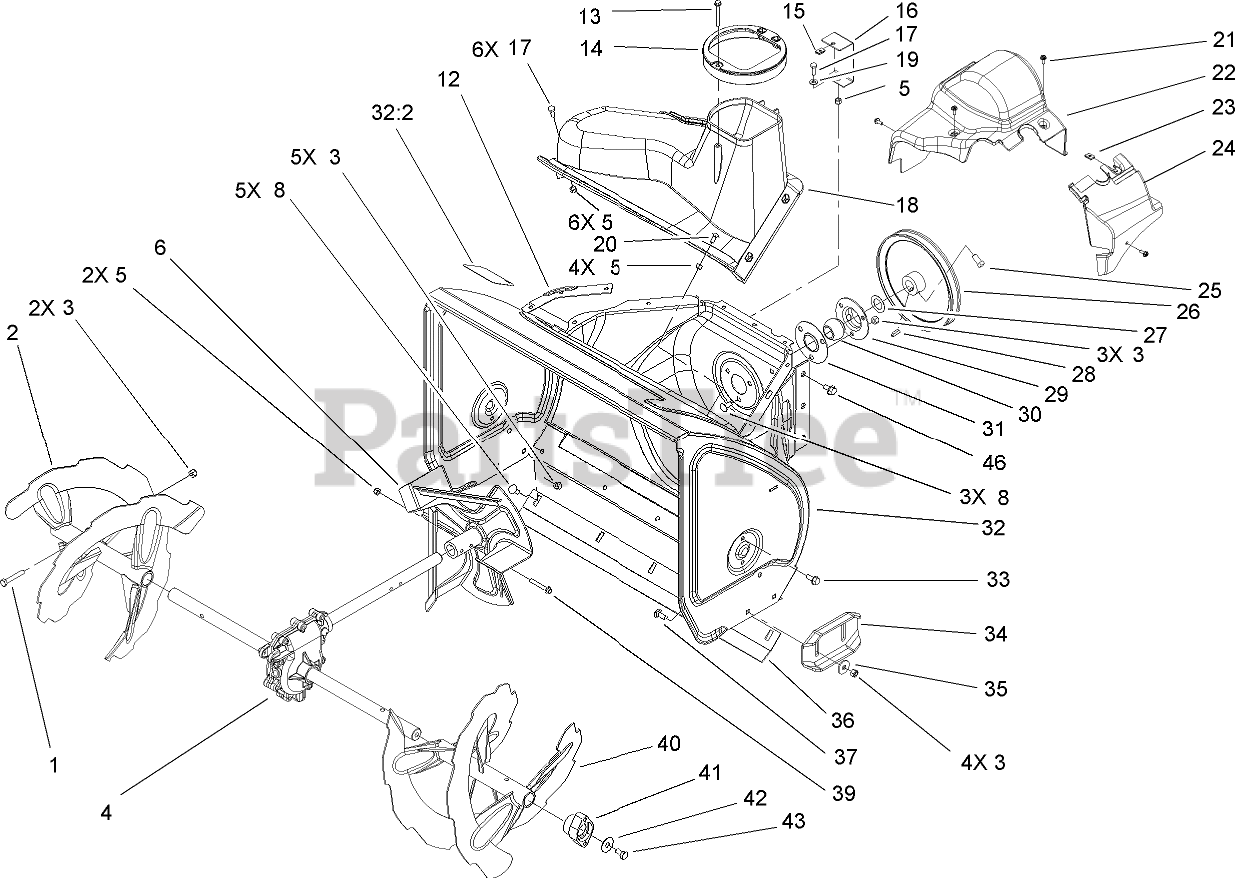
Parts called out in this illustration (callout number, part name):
1	SCREW-HH
2	RH AUGER ASM
3	NUT-LOCK, NI
4	26INCH AUGER GEARCASE ASM
5	NUT-LOCK, NI
6	IMPELLER ASM
8	SCREW-CARR
12	SEAL-FLANGE, COVER
13	SCREW-PLASTITE
14	GUIDE-CHUTE
15	NUT-SPEED, U-TYPE
16	BRACKET-COVER, CLIP NUT
17	SCREW-HH
18	COVER
19	WASHER-FLAT
20	BOLT-CARR
21	SCREW-HWH
22	COVER-BELT
23	NUT-SPEED
24	COVER-EXTENSION, BELT
25	SCREW-SET, SQH
26	PULLEY-IMPELLER
27	WASHER-THRUST
28	KEY-WOODRUFF
29	FLANGE-CUP, BEARING
30	BEARING-BALL
31	FLANGE-CUP, BEARING
32	HOUSING-AUGER, 26 INCH
32:2	DECAL-WARNING, AUGER
33	SCREW-HWHTF
35	WASHER
36	SCRAPER-FIXED
37	SCREW-CARR
39	SCREW-HHF
40	LH AUGER ASM
41	BEARING-AUGER
42	WASHER
43	SCREW-HH
46	SCREW-HWHTF
